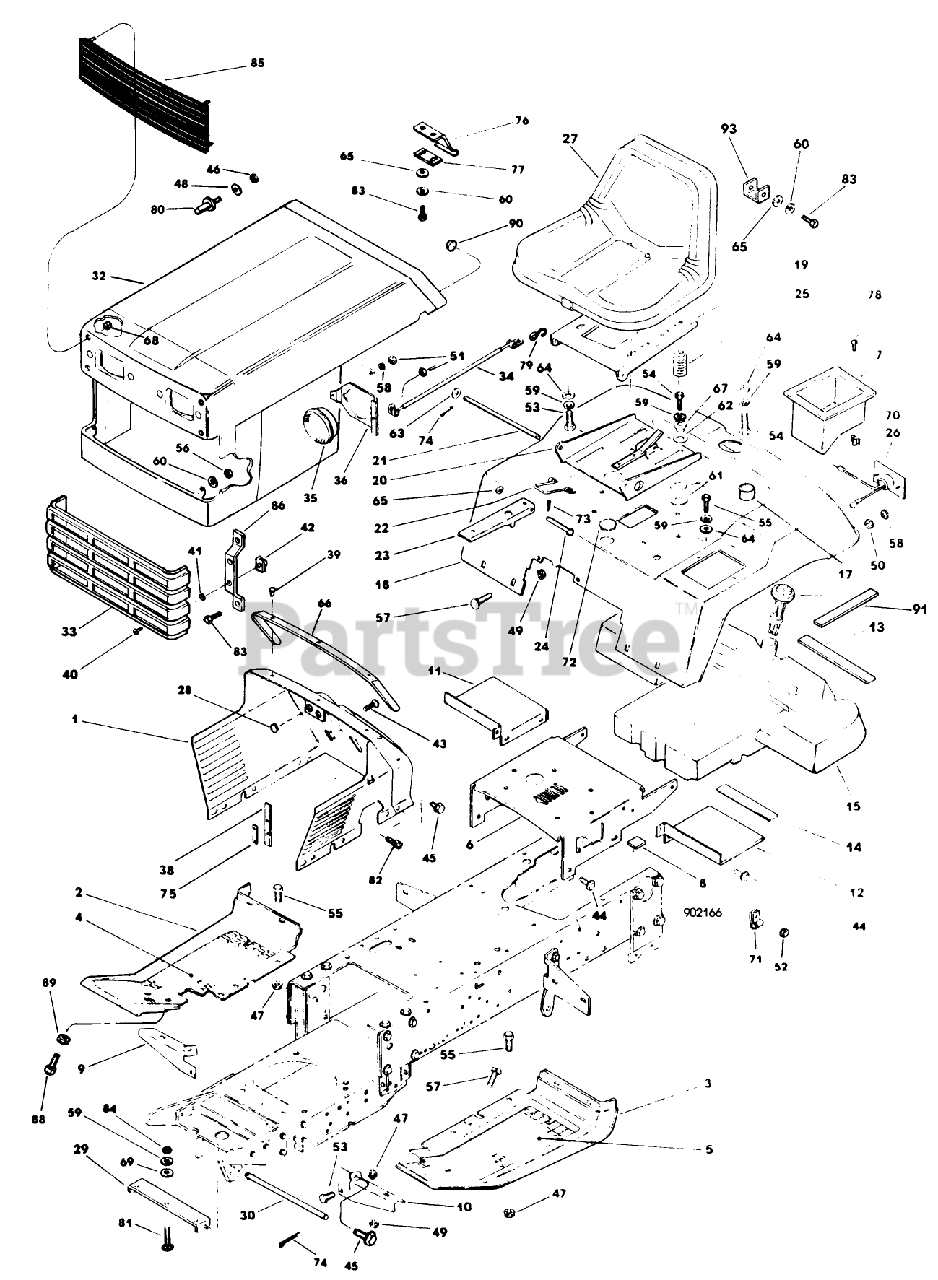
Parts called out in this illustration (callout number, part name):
1	Instrument Panel Decal Assembly
30	Rod-Hood Pivot
37	Unassigned No.
59	Lock Washer 5/16 Plated
78	Rivet
